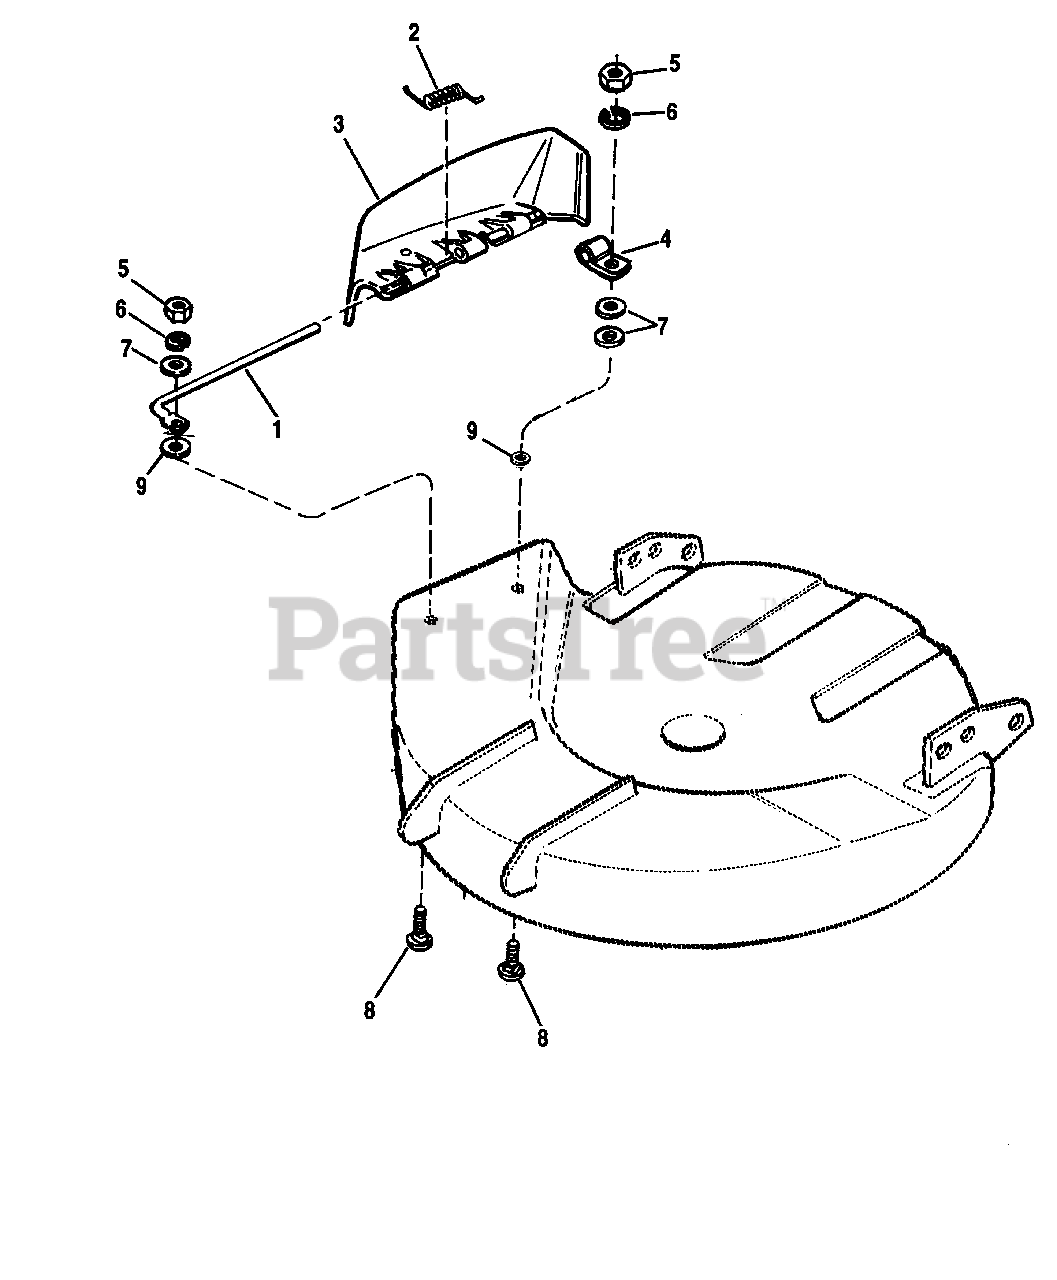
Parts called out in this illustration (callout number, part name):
1	ROD, Deflector
3	DEFECTOR, Plastic
5	NUT, Hex, 1/4-20
6	LOCKWASHER, 1/4
7	WASHER, Plain
8	CARRIAGE BOLT, 1/4-20 x 1-1/4
9	PUSHNUT, 1/4
